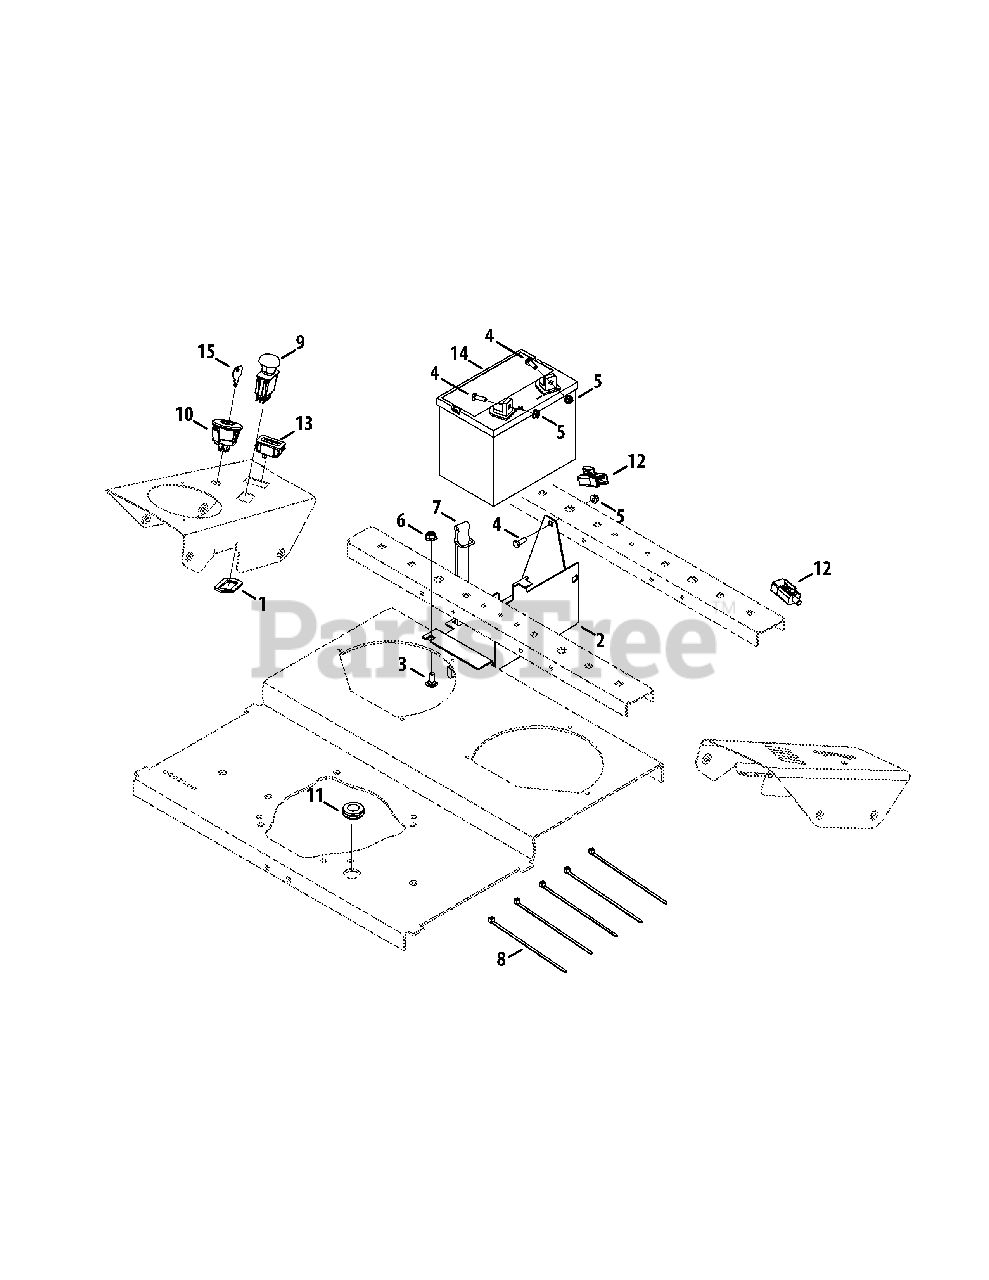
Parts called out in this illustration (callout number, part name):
1	PTO Switch Bracket
2	Battery Bracket
3	Carriage Bolt, 3/8-16 x .750
4	Hex Cap Screw, 1/4-20 x .75
5	Nut, 1/4-20, Flangelock
6	Nut, 3/8-16, Flangelock
7	Battery Strap
8	Cable Tie
9	Electric PTO Switch
10	Key Switch
11	Rubber Grommet, .75 x 1.062 x .50
12	Plunger Switch, NO/NC
13	Hour Meter, Kohler Efi
15	Key, Assembly
